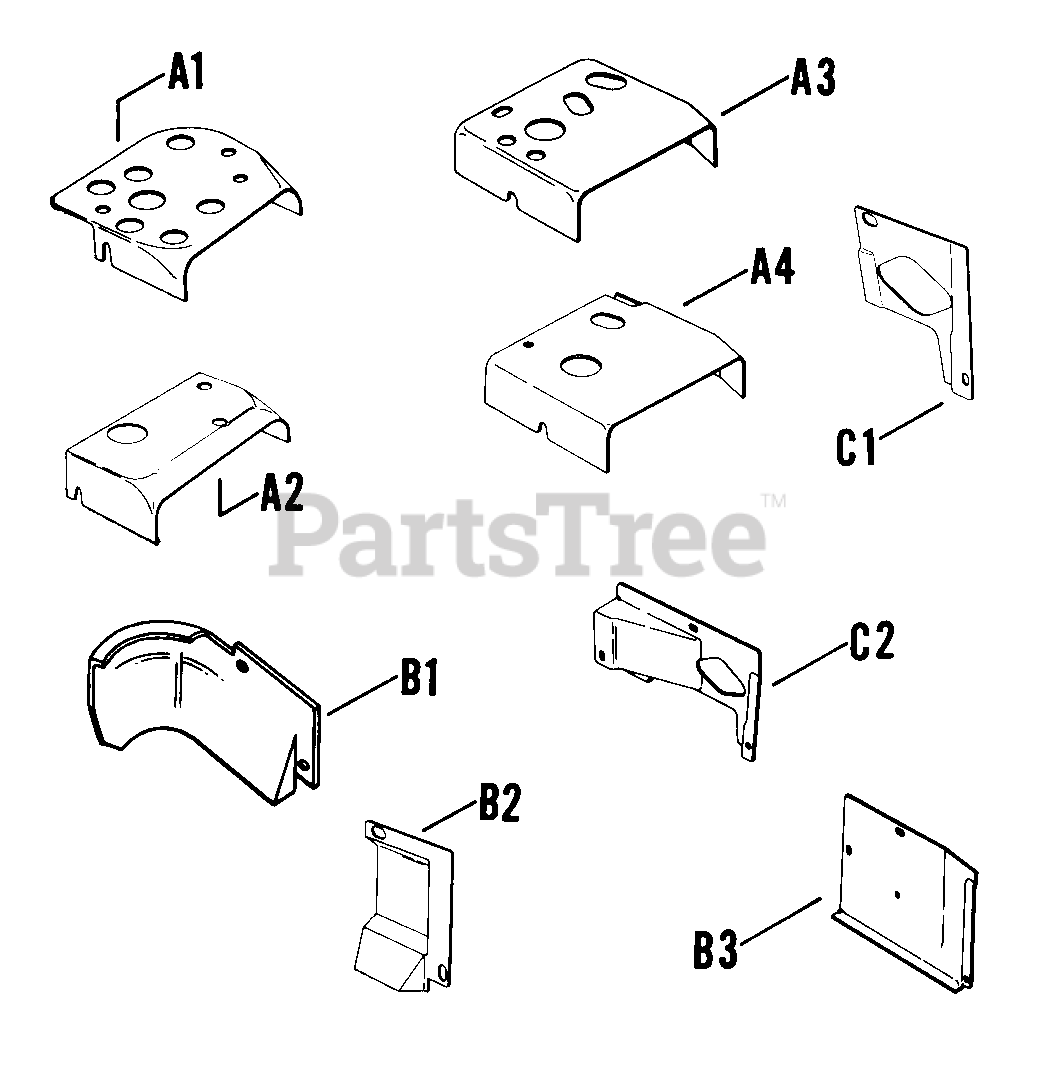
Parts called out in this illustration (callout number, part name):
A1	BAFFLE, HEAD - DISCONTINUED
B1	BAFFLE, CYLINDER AIR
C1	BAFFLE, SIDE AIR
